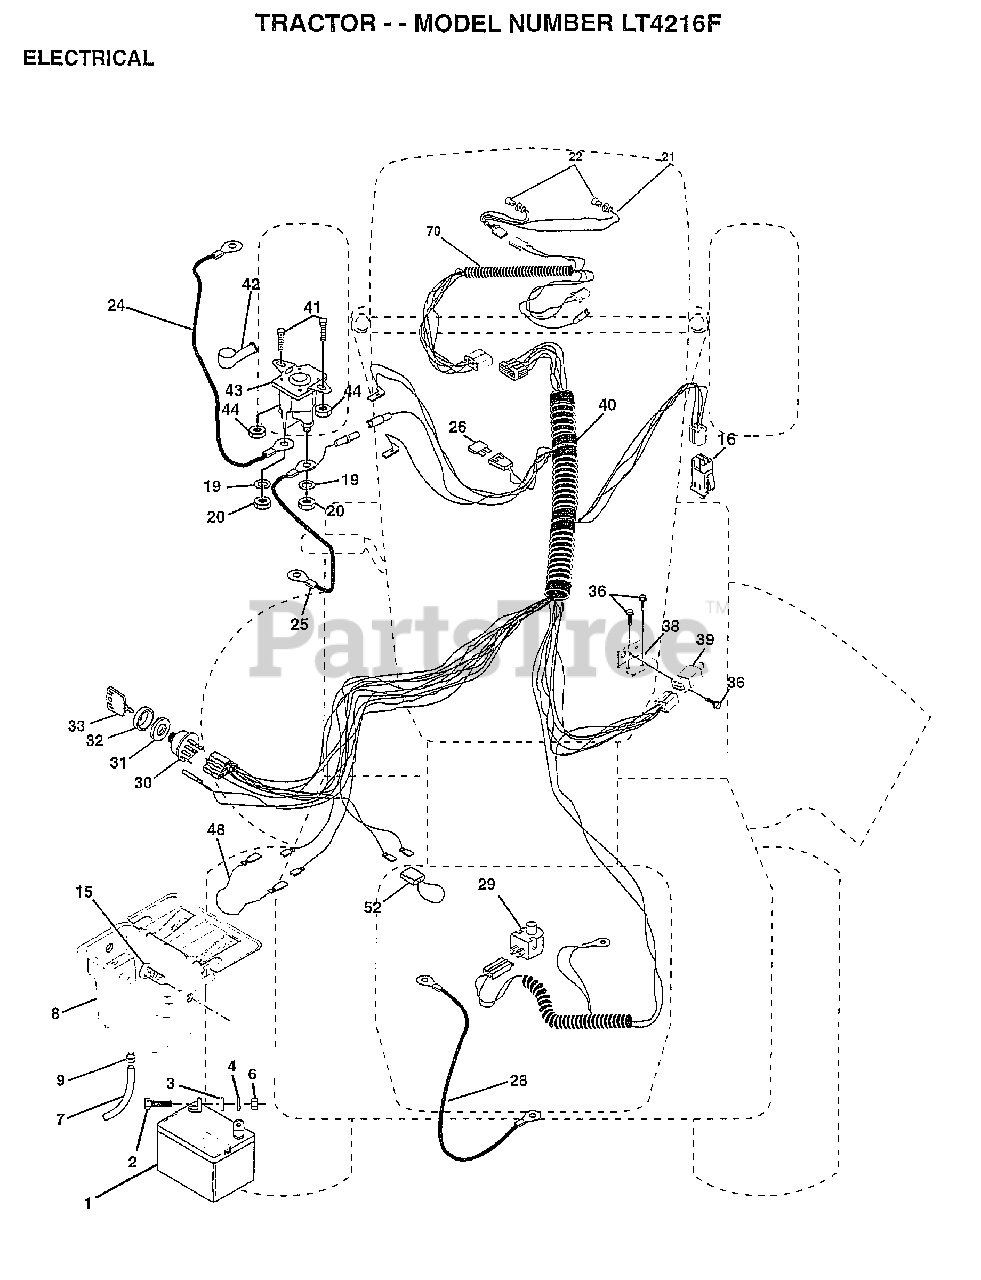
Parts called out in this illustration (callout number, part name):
2	BOLT LT
3	WASHER
4	LOCKWASHER
7	TUBE T
9	HOSE CLAMP T
15	FASTNER.SNAP-IN
16	SWITCH INTERLOCK
20	NUT
21	"HARNESS,LIGHT SOC"
22	HEADLAMP BULB
24	CABLE-BATTERY T
25	CABLE.BTRY.6GA.RD
26	FUSE HYT
28	CABLE T
29	SWITCH SEAT
30	SWITCH IGN 4POS
31	NUT IGNITION
32	COVER KEY SWITCH
33	KEY
36	SCREW
38	BRACKET SWITCH IN
39	SWITCH INTERLOCKT
40	HARNESS.IGNITION
41	BOLT HXHD FIN
44	NUT HXKEP 1/4X20
48	ADAPTER AMMETER
52	PROTECTION LOOP
70	HARNESS.ENG.LT.
